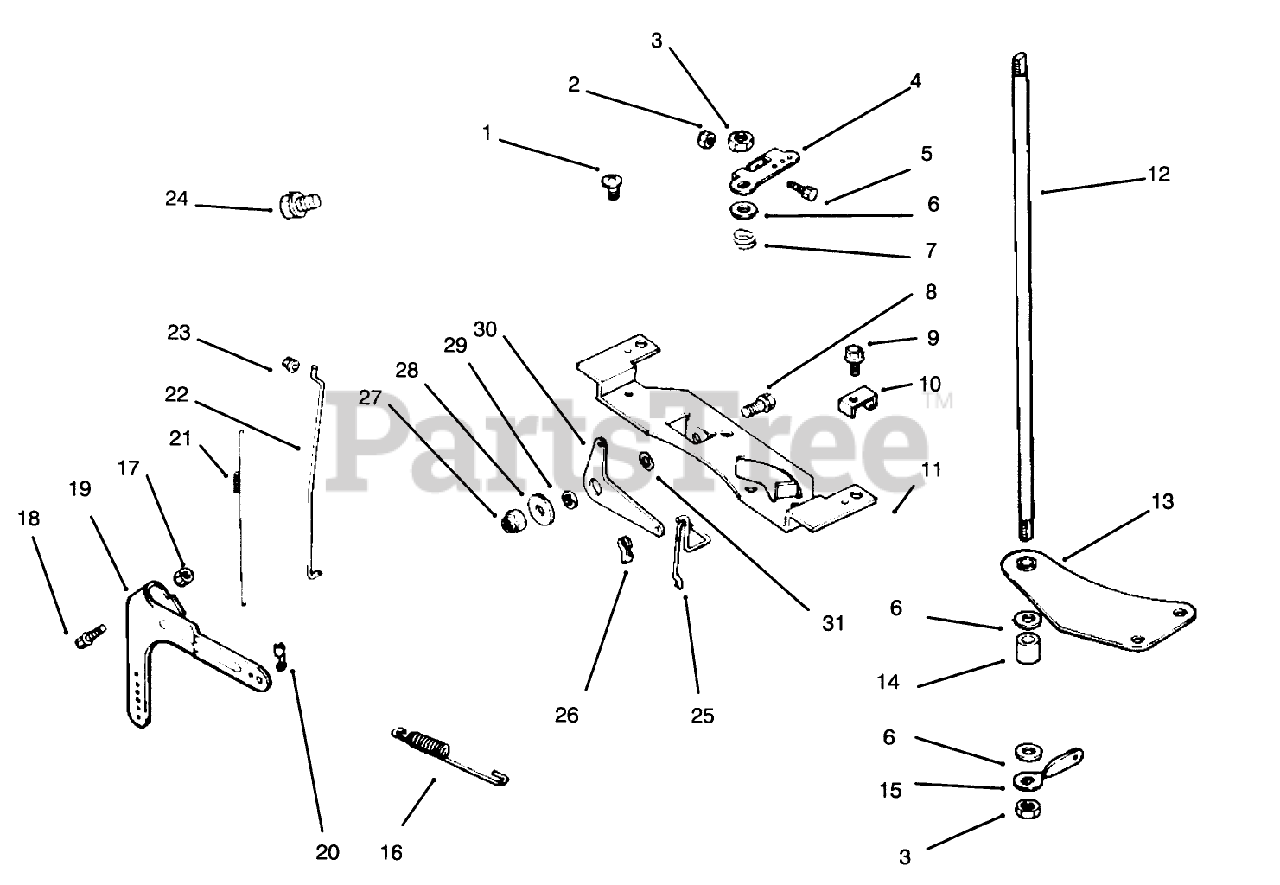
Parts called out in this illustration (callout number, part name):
1	Screw
2	Nut
3	Nut
4	Lever-Throttle Control
5	Screw
6	Washer
7	Spring-Throttle Shaft
8	Screw
9	Screw
10	Clamp
11	Bracket-Control
12	Shaft-Throttle
13	Bracket-Throttle Shaft
14	Spacer
15	Lever-Throttle Control
16	Spring-Governor
17	Nut
18	Screw
19	Lever-Govenor
20	Bushing-Linkage
21	Spring-Linkage
22	Linkage-Throttle
23	Bushing-Linkage
24	Screw
25	Linkage-Choke
26	Bushing-Linkage
27	Nut
28	Washer
29	Spacer
30	Lever-Choke
31	Washer
